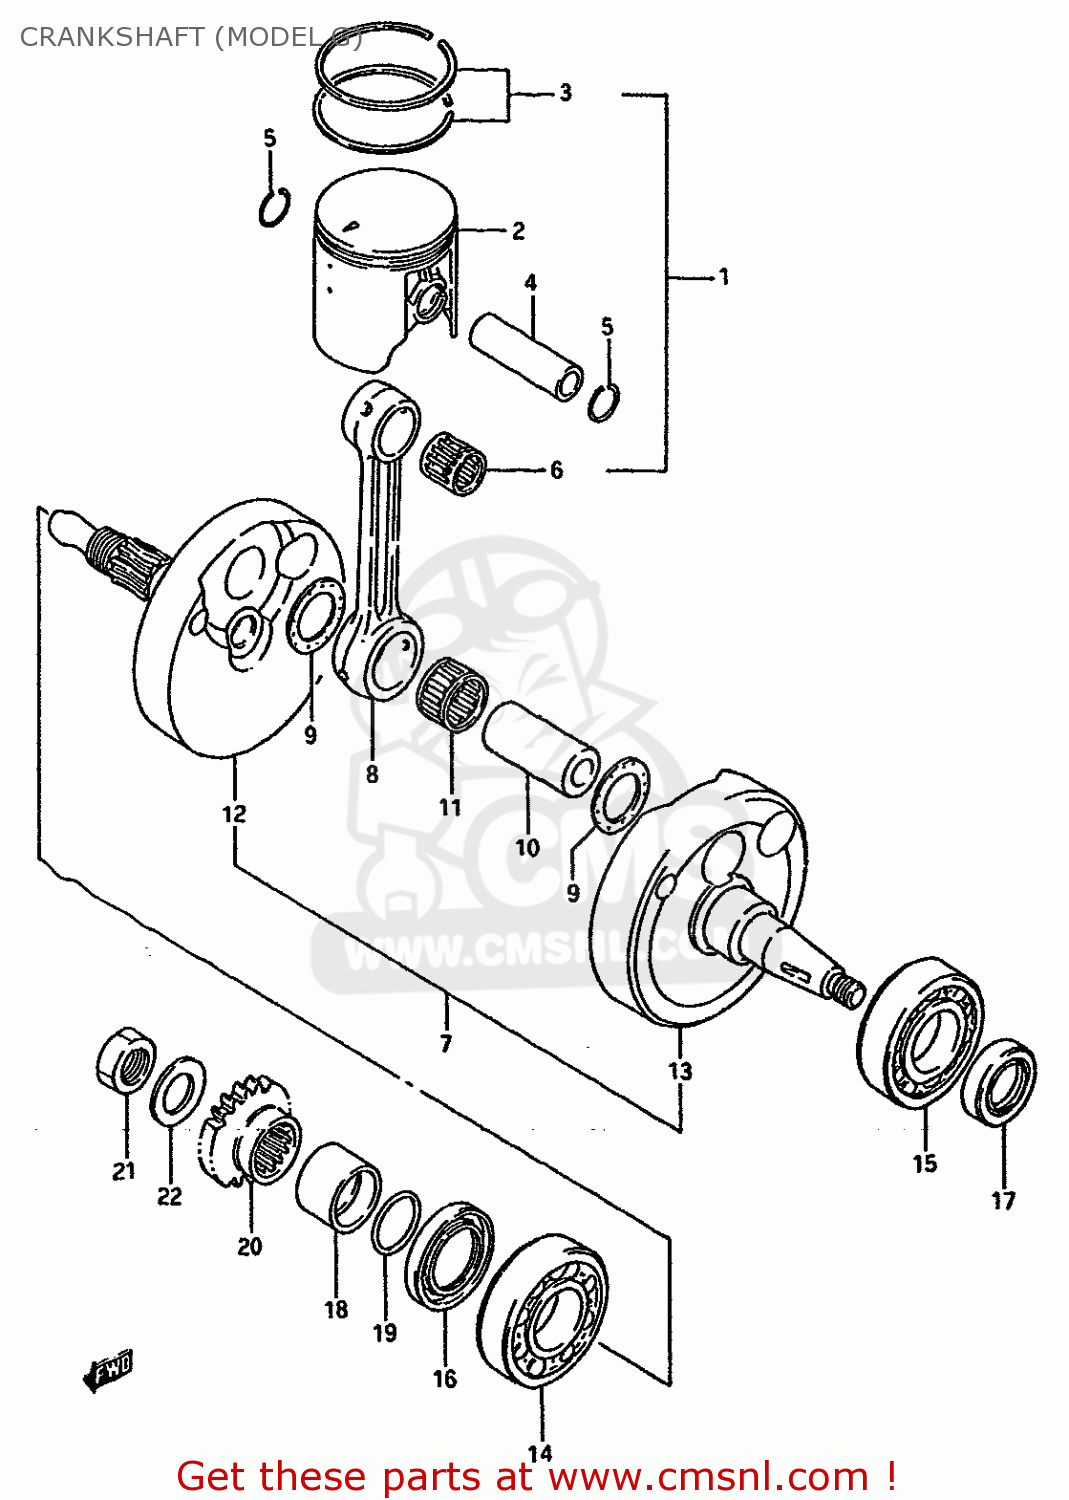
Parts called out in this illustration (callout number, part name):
1	PISTON SET(STD)
2	PISTON
3	RING SET,PISTON
4	PIN,PISTON
5	RING,SNAP 14MM
6	BEARING
7	CRANKSHAFT ASSY
8	CONNECTING ROD
9	WASHER(22X35X1)
10	PIN,CRANK
11	BEARING
12	CRANKSHAFT,R
13	CRANKSHAFT,LEFT
14	BEARING
15	BEARING(25X52X15)
16	SEAL,OIL(28X40X8)
17	OIL SEAL
18	SPACER,PRIMARY DRIVE GEAR
19	O RING(D:2.4,ID:19.8)
20	GEAR,PRIMARY DRIVE
21	NUT
22	WASHER
